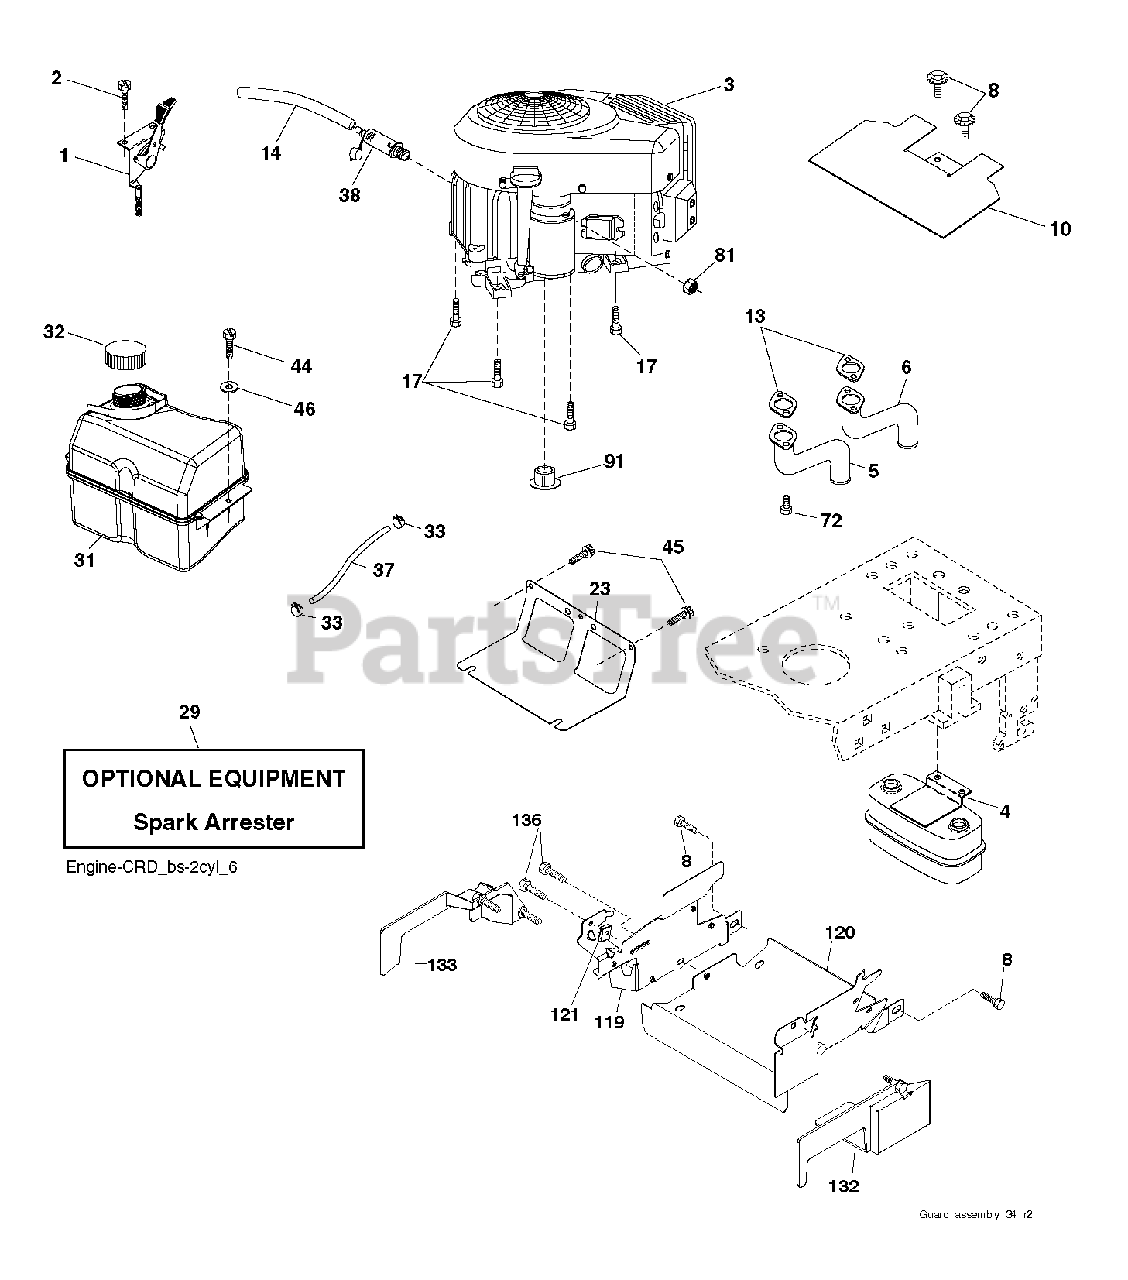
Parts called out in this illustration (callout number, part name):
1	CONTROL.TH/CK.COBRA.B&S.TWN.
2	SCREW.#10 X 0.750.BOS THREAD
4	MUFFLER.TWIN.CYL.LOW.TONE
5	EXHAUST TUBE RH
6	TUBE MANIFOLD LH
8	BOLT, 5/16-18 X 1 3/4
10	SHIELD.HEAT.MUFFLER
13	GASKET.MUFFLER
14	TUBE, DRAIN OIL ASM.
17	SCREW.3/8-16
23	SHEILD.BROWNING.DBR.GUARD
29	ARRESTER SPARK (OPTIONAL)
32	CAP ASM.FUEL.2.25"FR.
33	HOSE CLAMP
37	LINE.FUEL.20
38	VALUE.OIL.DRAIN
44	SCREW HEXWSHR 1/4-20X3/4
45	SCREW, 3/8-16X3/4
72	SCREW.SOCKET.HEAD.5/16-18
81	NUT
91	BUSHING.1.375OD
136	SCREW.1/4-20X5/8
